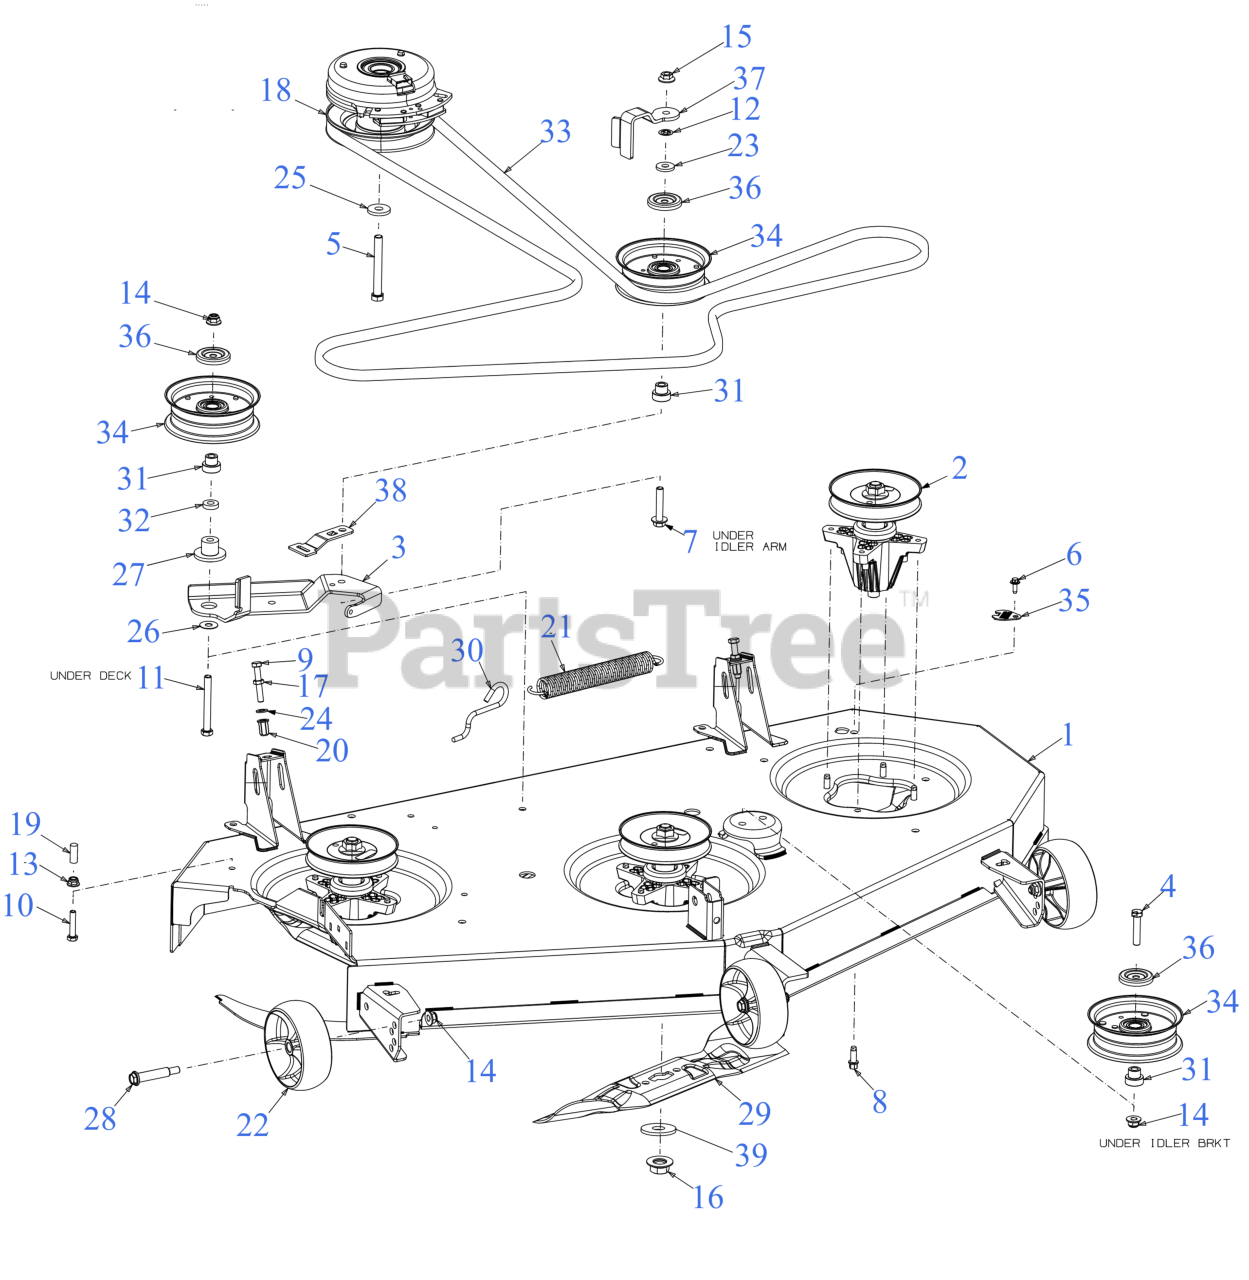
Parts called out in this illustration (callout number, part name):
1	50" FAB DECK SHELL
2	SPINDLE ASSEMBLY (5.37 DIA)
3	DECK IDLER BRACKET
4	HEX SCREW 3/8-16 x 1.75 GR5
5	SCREW 7/16-20 x 3.5 GR5
6	SCREW M6-1 x .625
7	SCREW 3/8-16 x 2.0
8	SCREW 5/16-18 x .875
9	SCREW-FULL THREAD 5/16-18 GR5
10	SCREW 5/16-18 x 1.5 LG
11	SCREW 3/8-16 x 3.25 GR8
13	FLANGE LOCK NUT 5/16-18
15	FLANGE LOCK NUT
16	HEX FLANGE NUT 5/8-18 GR5
18	ELECTRIC PTO CLUTCH
20	NUT RIVET 5/16-18
21	EXTENSION SPRING
22	DECK WHEEL (5.0 DIA x 1.875)
23	FLAT WASHER .385 x 1.00 x .135
24	FLAT WASHER
25	FLAT WASHER .445 x 1.248 x .170
26	FLAT WASHER
27	SHOULDER SPACER
28	SHOULDER BOLT (.50 X 2.0 x 3/8 -16)
29	17.271" BLADE (2IN1) (S SHAPE CENTER HOLE)
29	Cub Cadet 50" HI LIFT BLADE SET (S SHAPE CENTER HOLE)
29	Troy-Bilt 50" HI LIFT BLADE SET (S SHAPE CENTER HOLE)
29	17.271" XTREME BLADE (2IN1) (S SHAPE CENTER HOLE)
29	Cub Cadet 50" XTREME BLADE SET (S SHAPE CENTER HOLE)
29	Troy-Bilt 50" XTREME BLADE SET (S SHAPE CENTER HOLE)
29	17.271" LOW LIFT (S SHAPE CENTER HOLE)
29	Cub Cadet 50" LOW LIFT BLADE SET (S SHAPE CENTER HOLE)
29	Troy-Bilt 50" LOW LIFT BLADE SET (S SHAPE CENTER HOLE)
30	DECK SPRING HOOK
31	SHOULDER SPACER
33	V-BELT B SEC x 143.5 LG
33	Cub Cadet 50" DECK DRIVE BELT
33	Genuine Factory Parts 50" DECK BELT
34	IDLER PULLEY 4.50" DIA
35	DECK WASH PLUG
36	IDLER PULLEY CAP
37	BELT KEEPER
39	FLAT WASHER .635X1.585X.062 HDN
